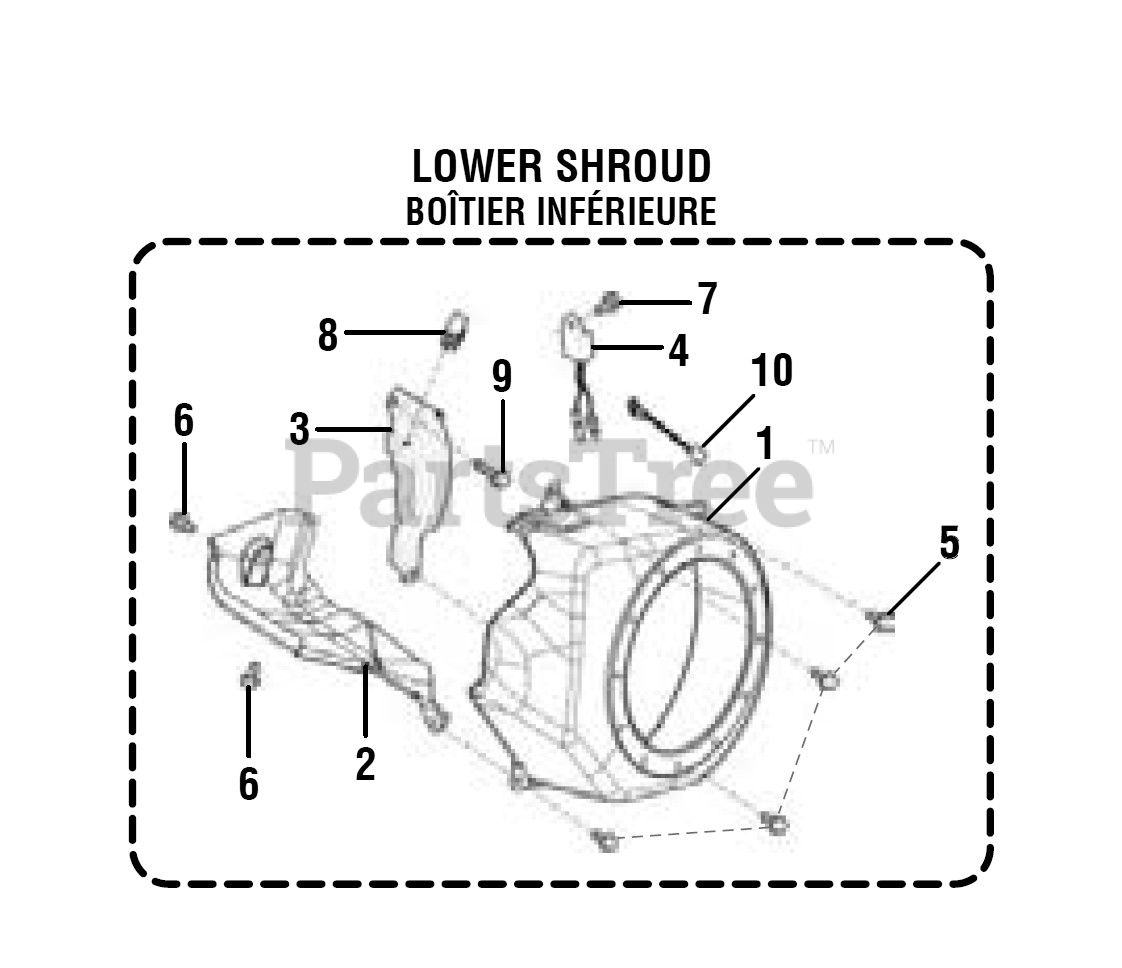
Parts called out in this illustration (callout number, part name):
2	Cylinder Body Shroud
3	Lower Shield
4	Oil Protector
8	Collar
10	Engine Stop Wire
